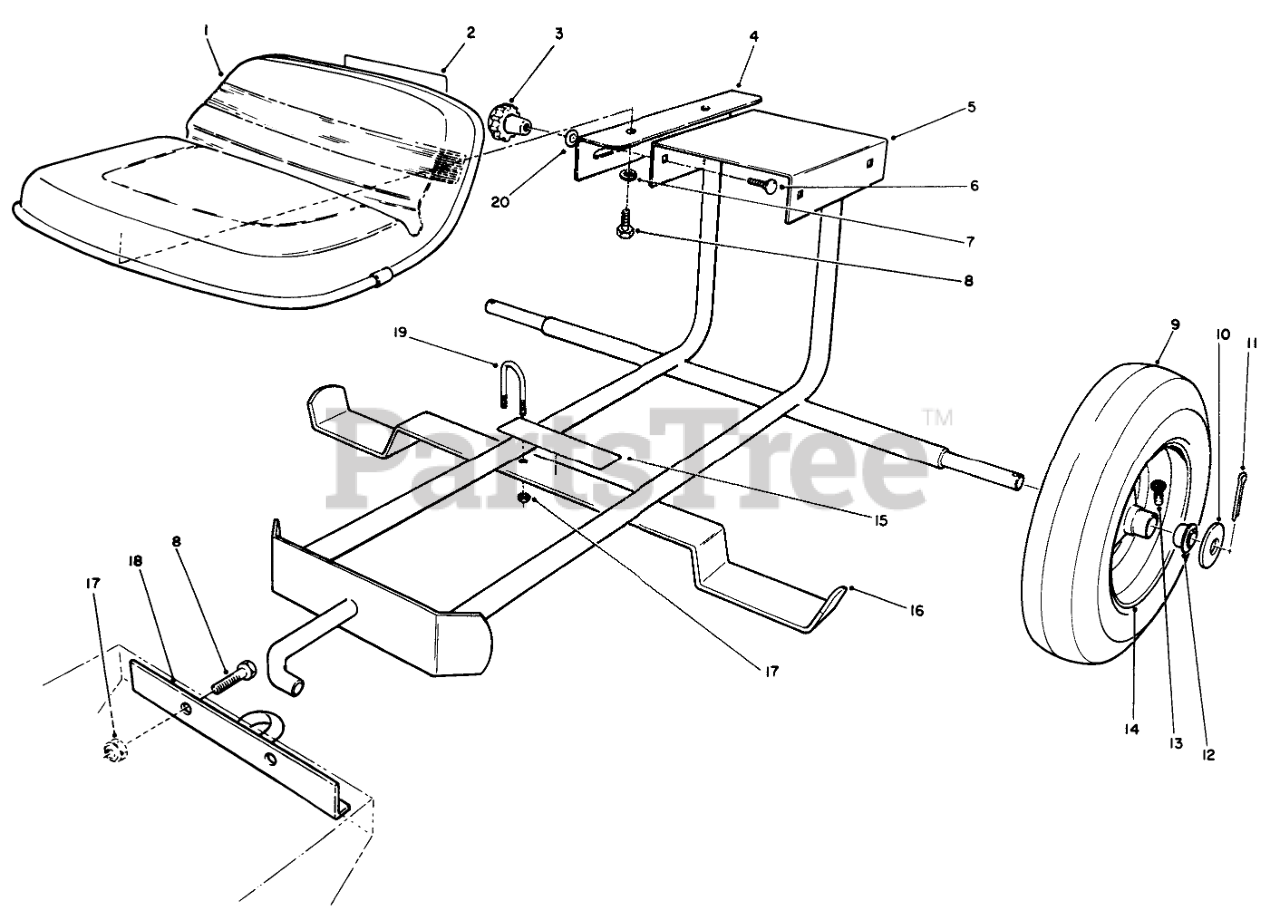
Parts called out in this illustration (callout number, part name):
1	Seat
2	DECAL
4	BRACKET R
5	Frame Assembly
6	BOLT-CARR
7	WASHER-LOCK
8	SCREW-HH
10	WASHER-FLAT
11	PIN-COTTER
12	BEARING
13	VALVE STEM-INNER TUBE
14	WHEEL
15	SULKY DECAL
16	SULKY FOOTREST R
17	NUT-LOCK, NI
18	HITCH
19	U-BOLT
20	WASHER-BELLEVILLE
